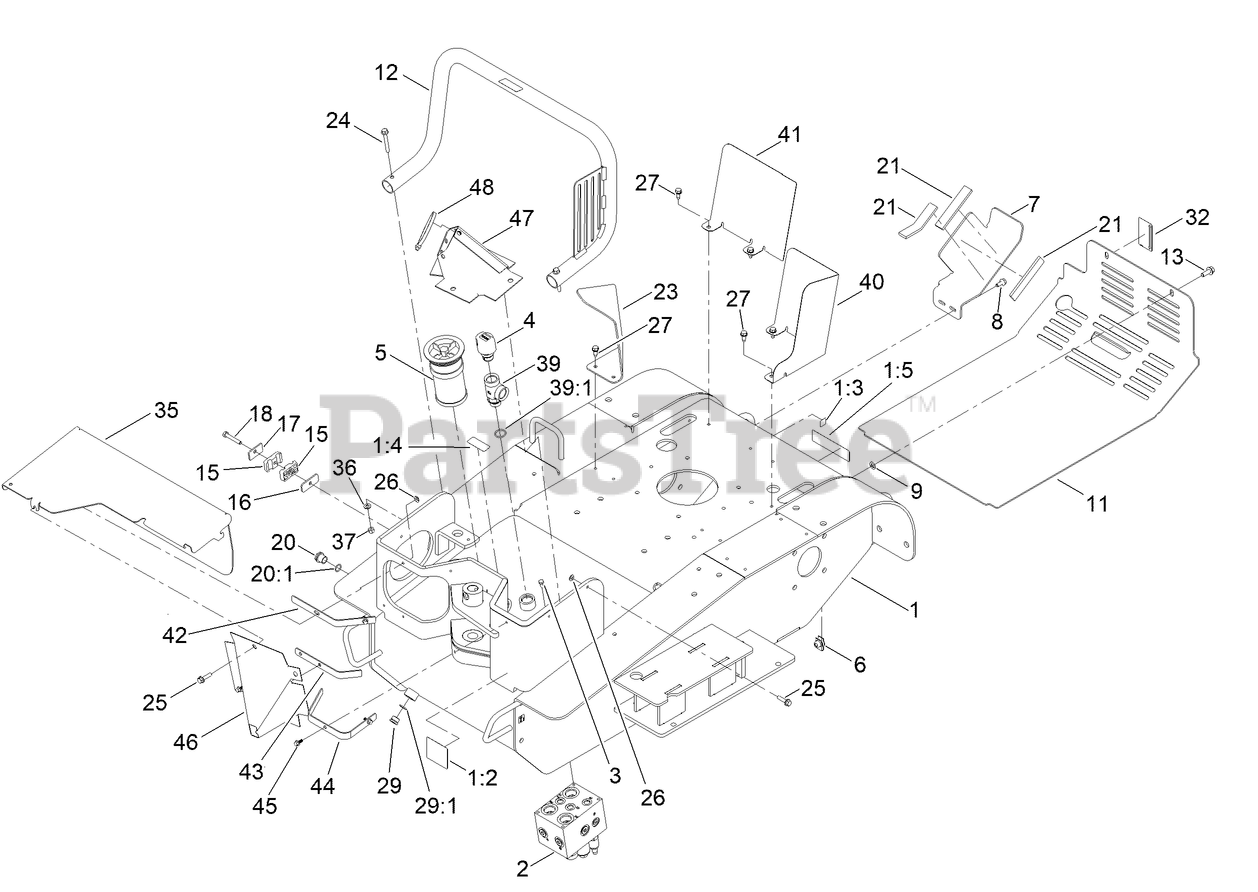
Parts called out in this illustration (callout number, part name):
1	FRAME-MAIN
1:2	DECAL-WARNING
1:3	DECAL-POINT, LIFT
1:4	DECAL-OIL, HYD
1:5	DECAL-DANGER
2	VALVE-CUTTER
3	SCREW-HH
4	BREATHER
5	CARTRIDGE-FILTER
6	NUT-TINNERMAN
7	BRACKET-TANK
8	SCREW-HHF
9	NUT-PUSH
11	COVER-REAR
12	MUFFLER GUARD DECAL ASM
13	SCREW-HHF
15	CLAMP-TUBE
16	PLATE-CLAMP
17	COVERPLATE
18	SCREW-HH
20	SIGHT GLASS ASM
20:1	O-RING
21	PAD-FOAM
23	PLATE-DEFLECTOR, RH
24	SCREW-HHF
25	SCREW-HHF
26	NUT-PUSH
27	SCREW-HWHTF
29	PLUG-HEX
29:1	O-RING
32	DECAL-BRAKE, PARKING
35	COVER, HYDRAULIC
36	WASHER-PLAIN
37	NUT-LOCK, NI
39	FITTING-TEE
39:1	O-RING
42	BRACKET-FRAME, TOP
43	BRACKET-FRAME, BOTTOM
44	BRACKET-BOOT
45	SCREW-HHF
46	COVER, CANVAS CYLINDER
47	COVER, CANVAS HYD HOSES
48	TIE-CABLE
